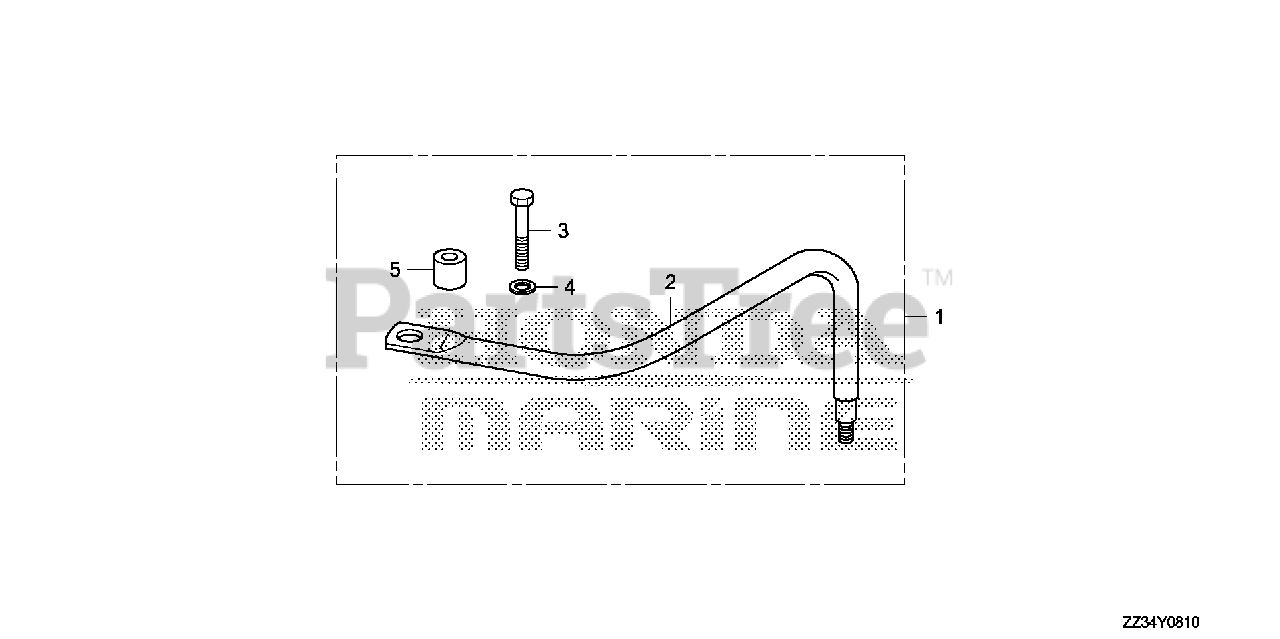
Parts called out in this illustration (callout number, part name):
1	ROD KIT, STEERING
2	ROD, STEERING
3	BOLT, HEX. (6X35)
4	WASHER, PLAIN (6MM)
5	COLLAR, DISTANCE (6.5X16X16.5)
